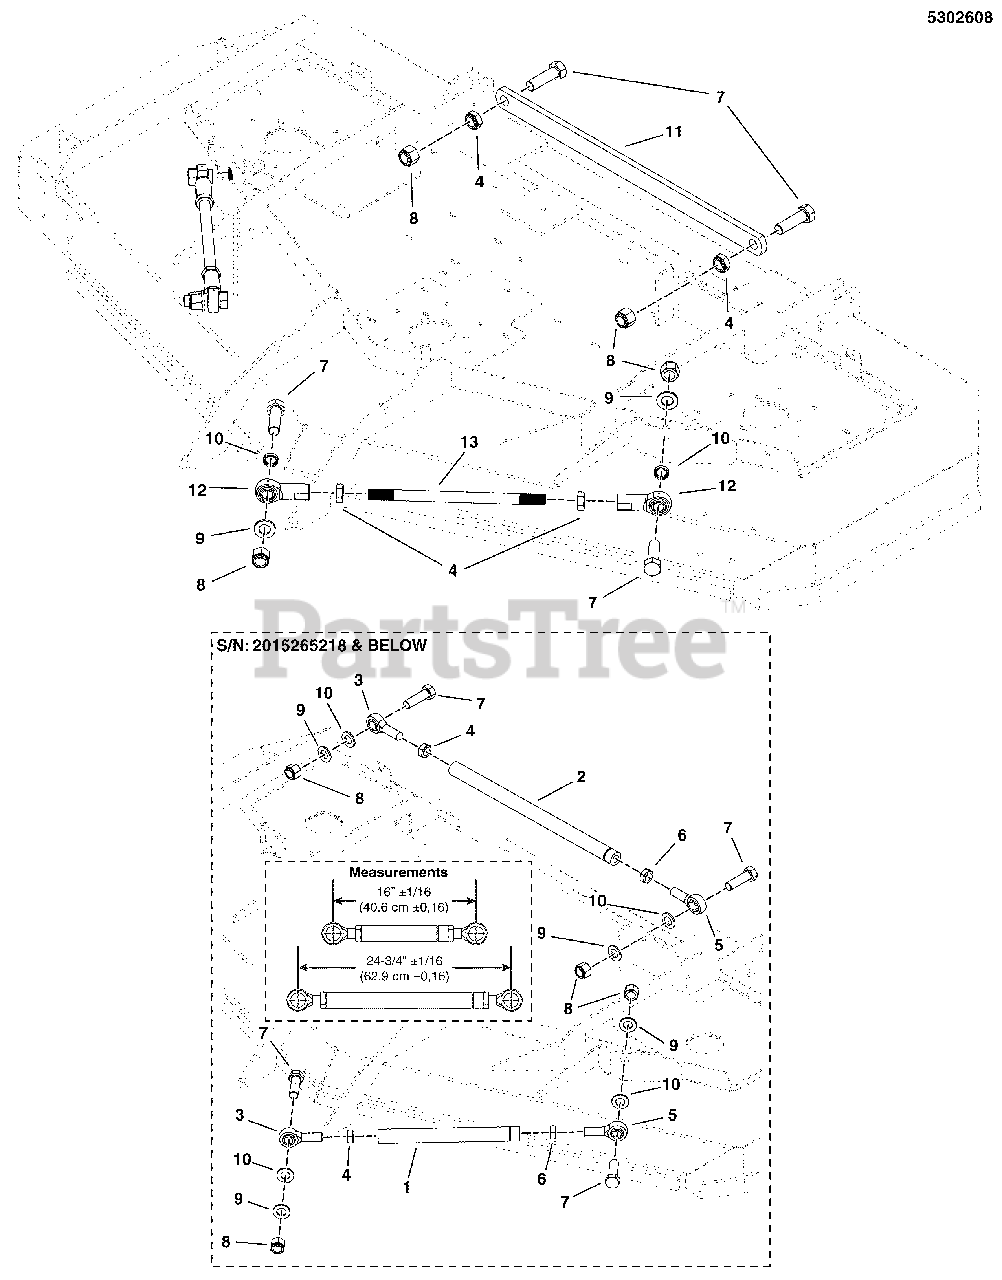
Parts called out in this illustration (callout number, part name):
1	ROD, DECK STABILIZER, 12.31" CZ
2	ROD, DECK STABILIZER, 19.91" CZ
3	BALL JOINT, 3/4-16, MALE
4	NUT, 3/4-16 HEX JAM
5	BALL JOINT, 3/4-16 MALE, LH
6	NUT, 3/4-16 HEX JAM, LH
7	BOLT, 3/4-16 X 2-1/2 YZ GD5
8	NUT, 3/4-16 HEX NYLON LOCK
9	WASHER, 3/4 SAE
10	SPACER, .76 X 1.00 X .25
11	BAR, PAN HARD, S200XT-RED
12	BALL JOINT, 3/4-16, FEMALE
13	ROD, 3/4-16 X 12.31
